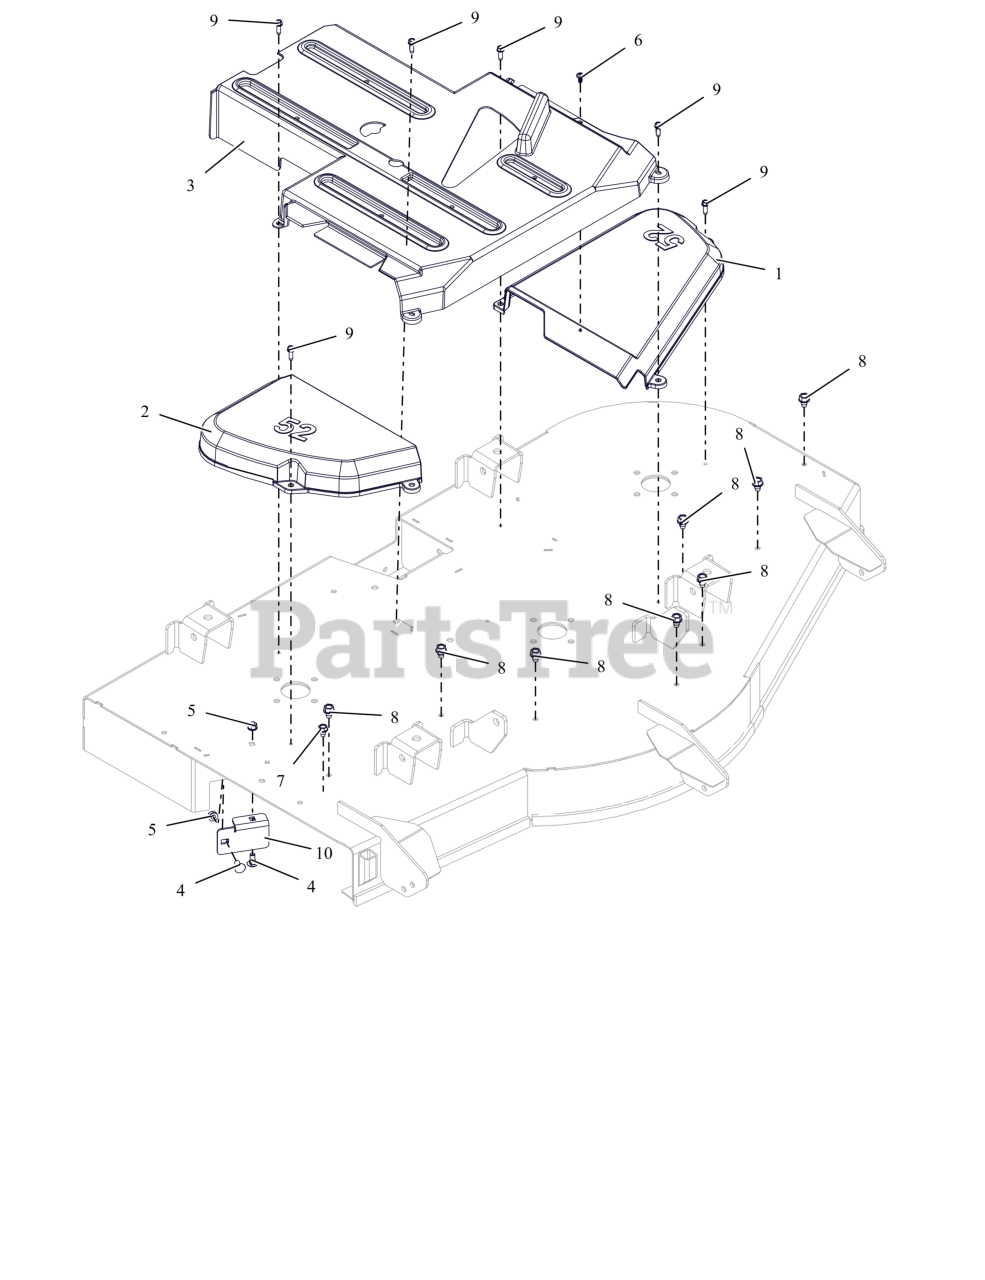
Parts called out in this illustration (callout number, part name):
1	COVER, BELT 52" LH
2	COVER, BELT 52" RIGHT
3	GUARD, CENTER, DECK
4	BLT,RHSN .31-18X.75 G5 ZCC
5	NUT-LK-TOP-FLG .312-18 GF ZCC
6	SCR-PAN .25-15X.50 6L H/LZB500
7	SCR,TAP .312-18X.50 HWH TR ZCC
8	SCR,TAP .375-16X.50 HWH TR ZCC
9	SCR,TAP .25-20X.75 HWH TR ZCC
10	STRIP, DEFLECTOR - 52"
